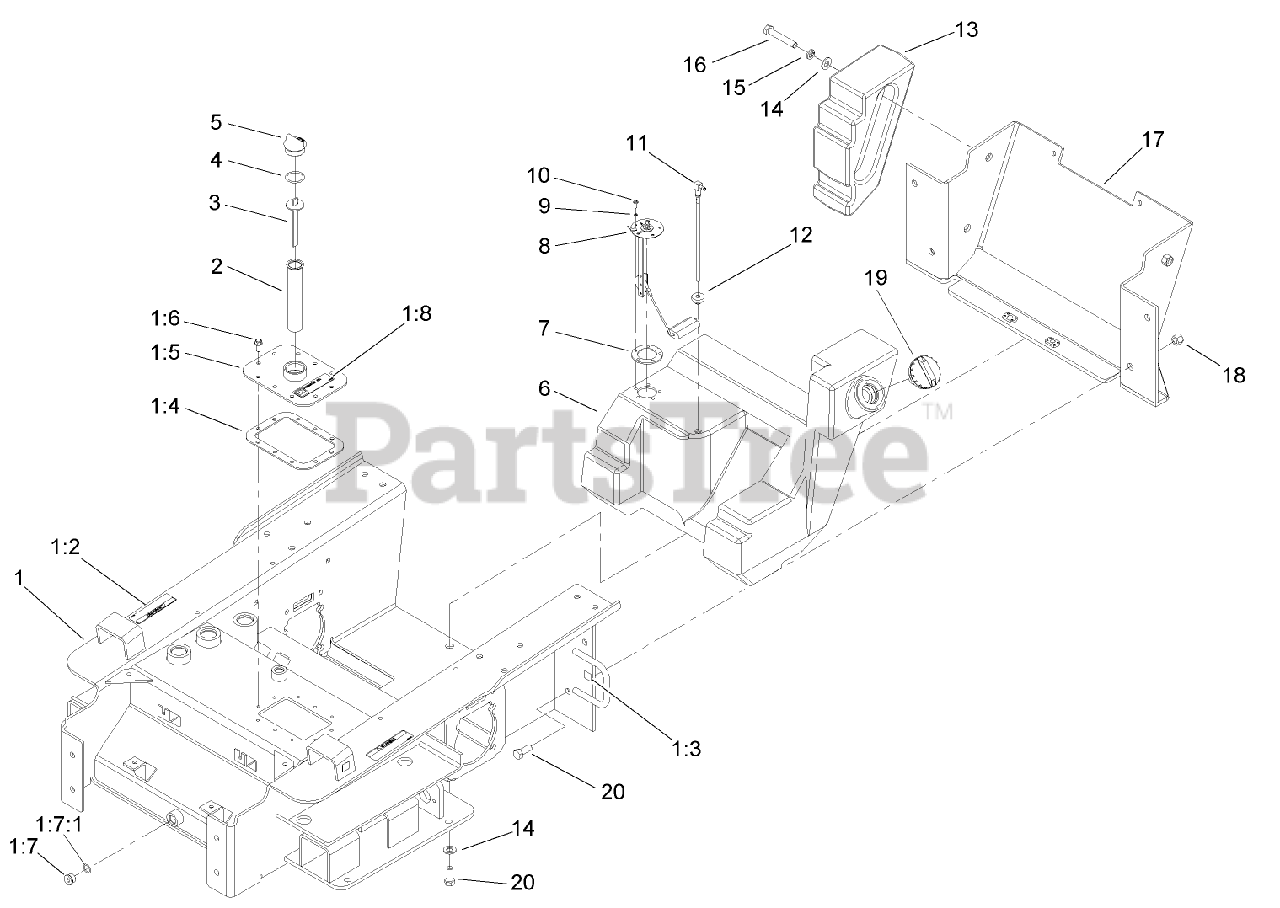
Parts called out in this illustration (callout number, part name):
1	CHASSIS ASM
1:2	DECAL-WARNING, PINCH
1:3	DECAL-POINT, LIFT
1:4	GASKET-COVER, ACCESS
1:5	TANK COVER ASM
1:6	SCREW
1:7	PLUG-HEX
1:7:1	O-RING
1:8	DECAL-OIL, HYD
2	FILTER-SCREEN
3	DIPSTICK-OIL
4	O-RING
5	PLUG-PLASTIC
6	TANK-FUEL
7	GASKET-SENDER, FUEL
8	SENDER-FUEL
9	WASHER-LOCK
10	SCREW-PPH
11	PIPE-STAND
12	BUSHING
13	COUNTERWEIGHT-REAR
14	WASHER-FLAT
15	WASHER-LOCK
16	SCREW-HH
17	REAR CHASSIS COVER ASM
18	NUT-LOCK, NI
19	CAP-FUEL
20	SCREW-HH
